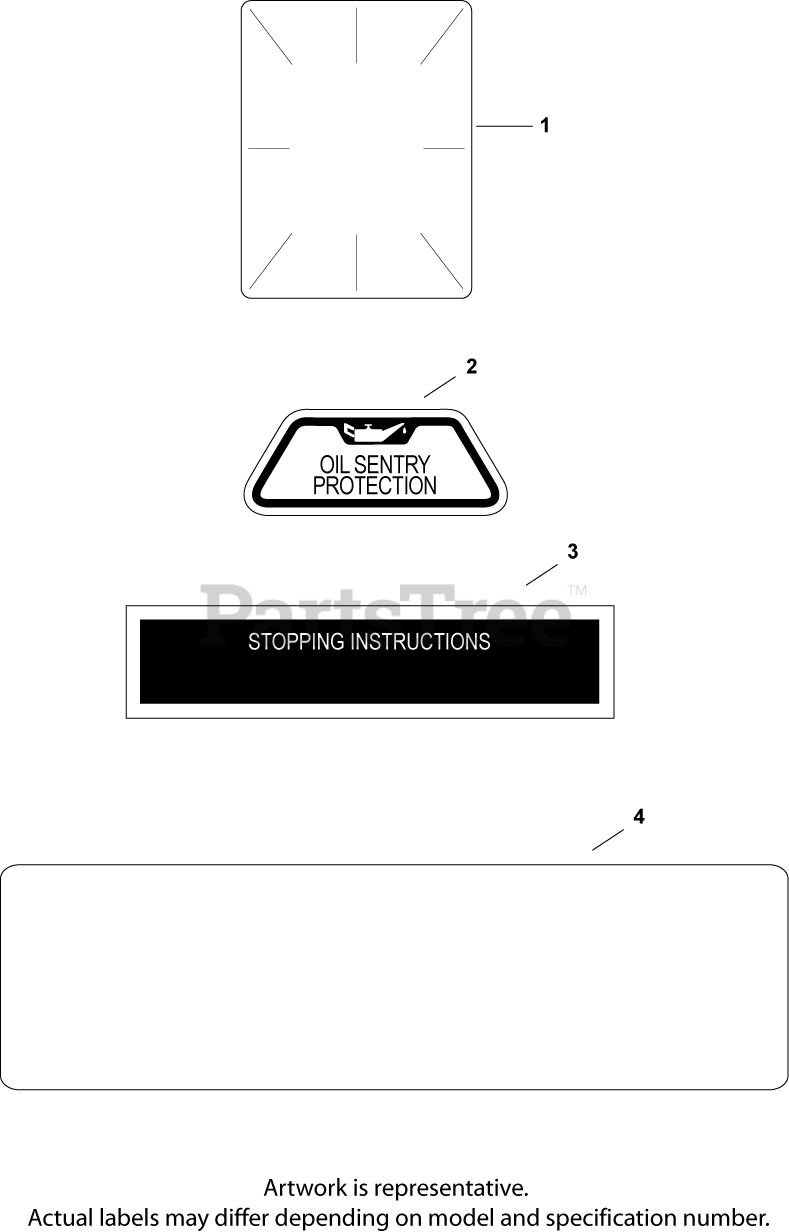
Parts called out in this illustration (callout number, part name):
1	DECAL, CLEAR LAMINATE USE 25 113 70-S
2	DECAL, OIL SENTRY - (#DSC)
3	DECAL, OIL SENTRY - (#DSC)
4	DECAL, 22 HP
